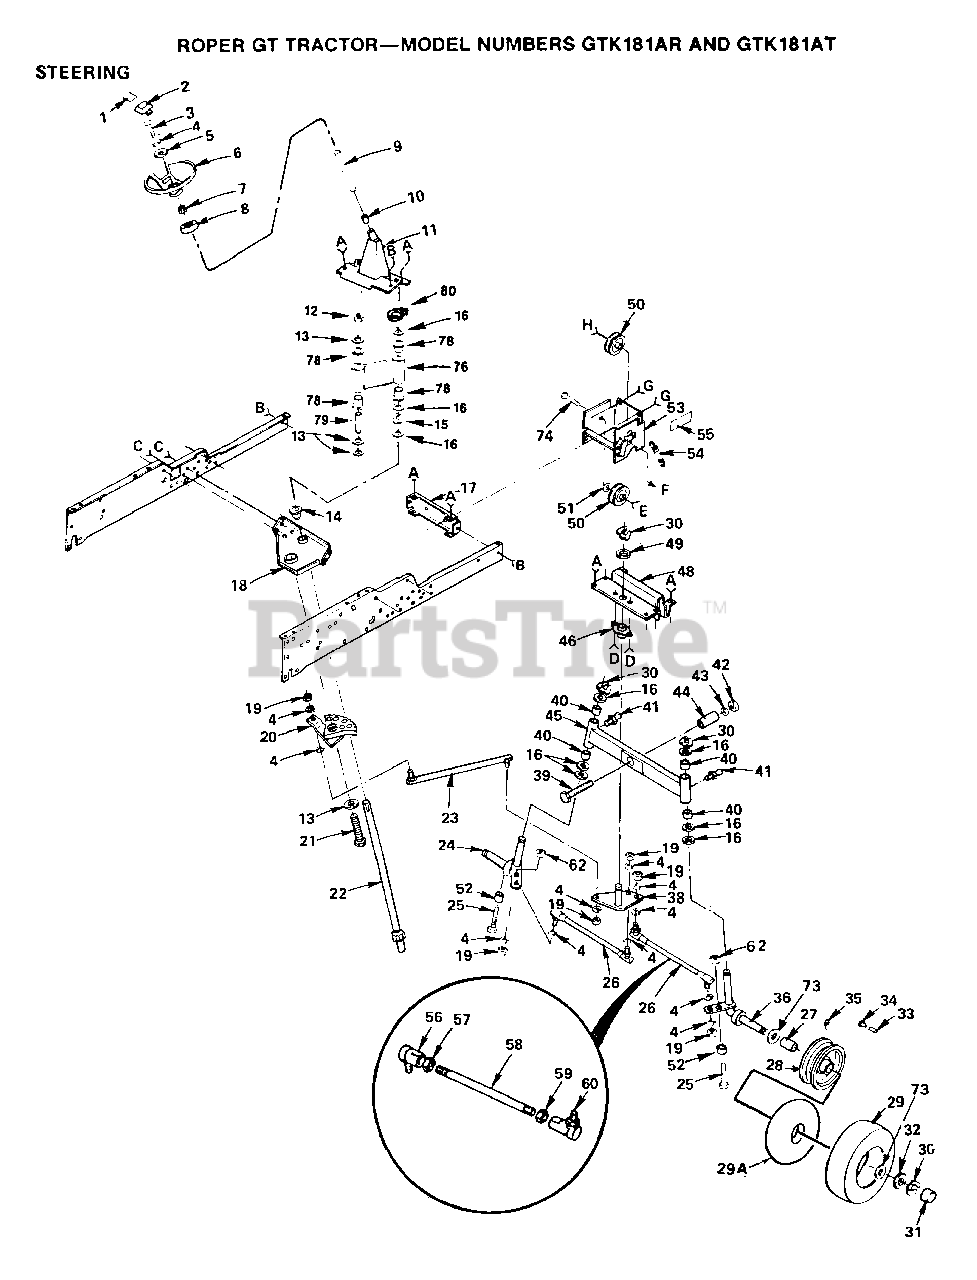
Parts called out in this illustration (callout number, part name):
1	DECAL - STEERING WHEEL
2	INSERT-WHEEL LT
3	BOLT
4	LOCKWASHER
5	WASHER T
7	ADAPTER LT
9	TUBE
10	"T, BEARING"
11	SUPPORT ASSY T
12	NUT LTV
13	WASHER GT
14	"FLANGE GT, BEAR."
15	KLIP RING
16	WASHER .T
17	FRAME BRACKET GT
20	SECTOR T
21	BOLT T
22	SHAFT STEERING GT
23	LINK.DRAG.T
24	SPINDLE ASSY T
25	BOLT, HEX 3/8 - 16 X 2
26	TIE ROD T
27	"FLANGE, BEARING"
29A	TUBE.16X6.5/7.5-8
30	RING
31	HUB CAP
33	VALVE CAP
34	VALVE STEM LT
35	FITTING LT
36	SPINDLE RH T
38	"T, BELLCRANK"
39	BOLT
40	BRNG. T
41	ZERK M
42	NUT X
43	WASHER
45	AXLE ASSEMBLY
48	AXLE BRACKET T
49	WASHER
50	IDLER-INSIDE T
51	WASHER T
53	IDLER BRKT T
54	SPRING
57	NUT
59	NUT
78	NYLINER T
